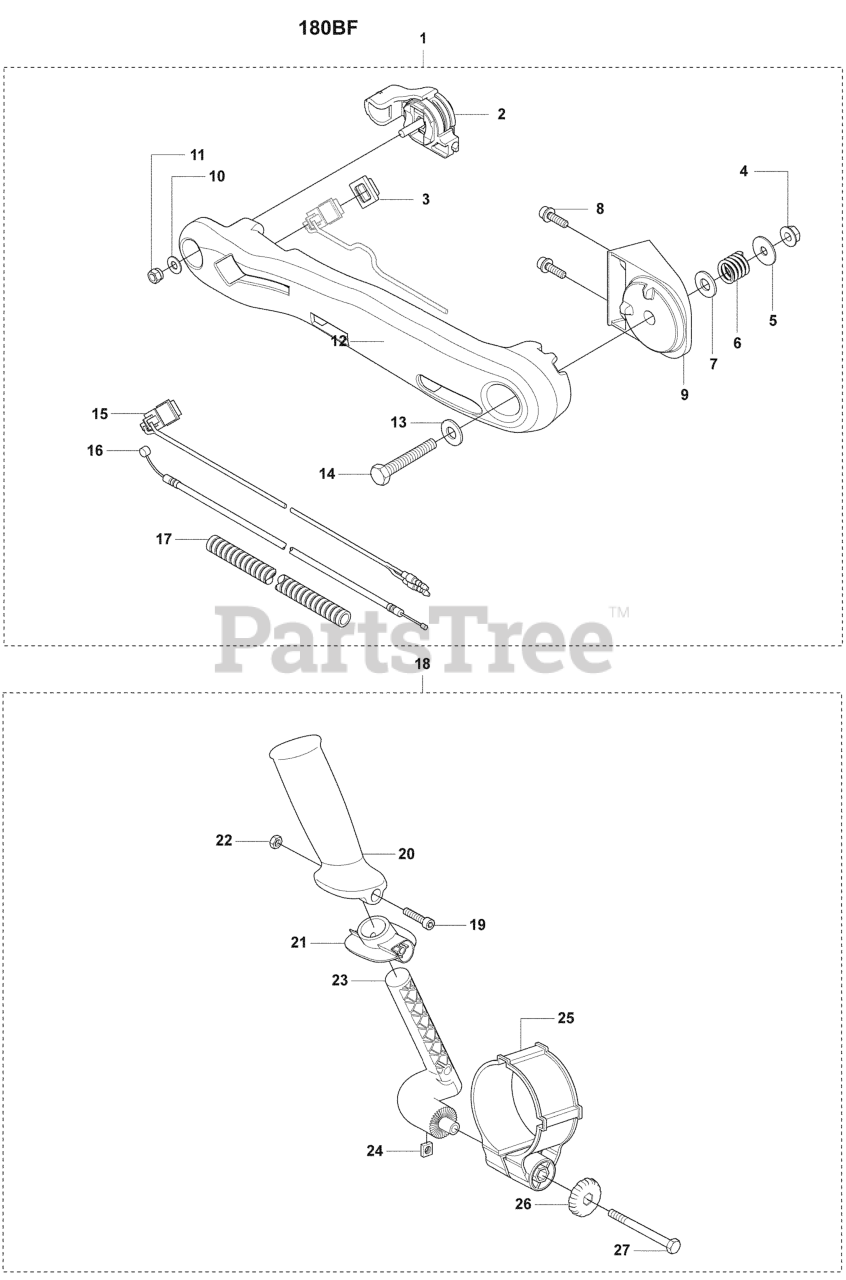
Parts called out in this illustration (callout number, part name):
1	LEVER
2	LEVER
3	CAP
4	NUT
5	WASHER
6	SPRING
7	WASHER
8	SCREW
9	RP_BRACKET
11	NUT
12	ARM
13	WASHER
14	BOLT
16	CABLE COMP
19	SCREW
23	BRACKET
25	HOLDER TH
